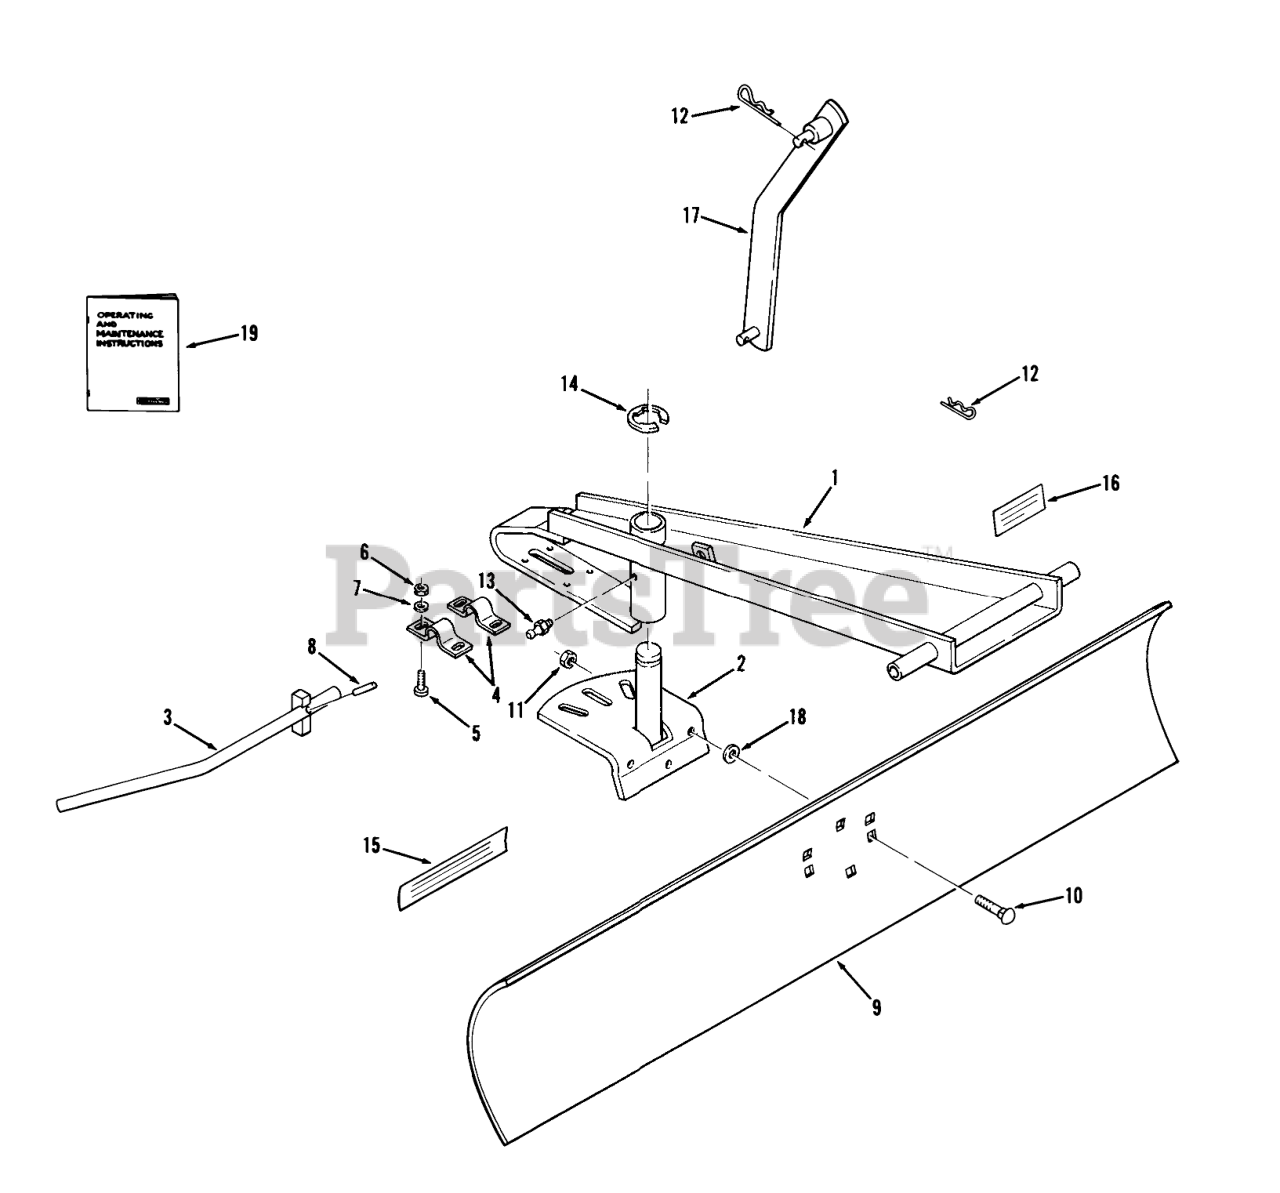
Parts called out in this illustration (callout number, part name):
1	Frame Assembly
2	Blade Support
3	Rod-Angle Adjustment
4	Bracket
5	Screw
6	Nut
7	WASHER
8	PIN-ROLL
9	Blade
10	Bolt
11	Nut
12	Hairpin
13	Zerk
14	E RING
15	DECAL-WHEEL HORSE
16	Caution Decal
17	Lift Link
18	Washer
19	Operating and Maintenance Instructions
